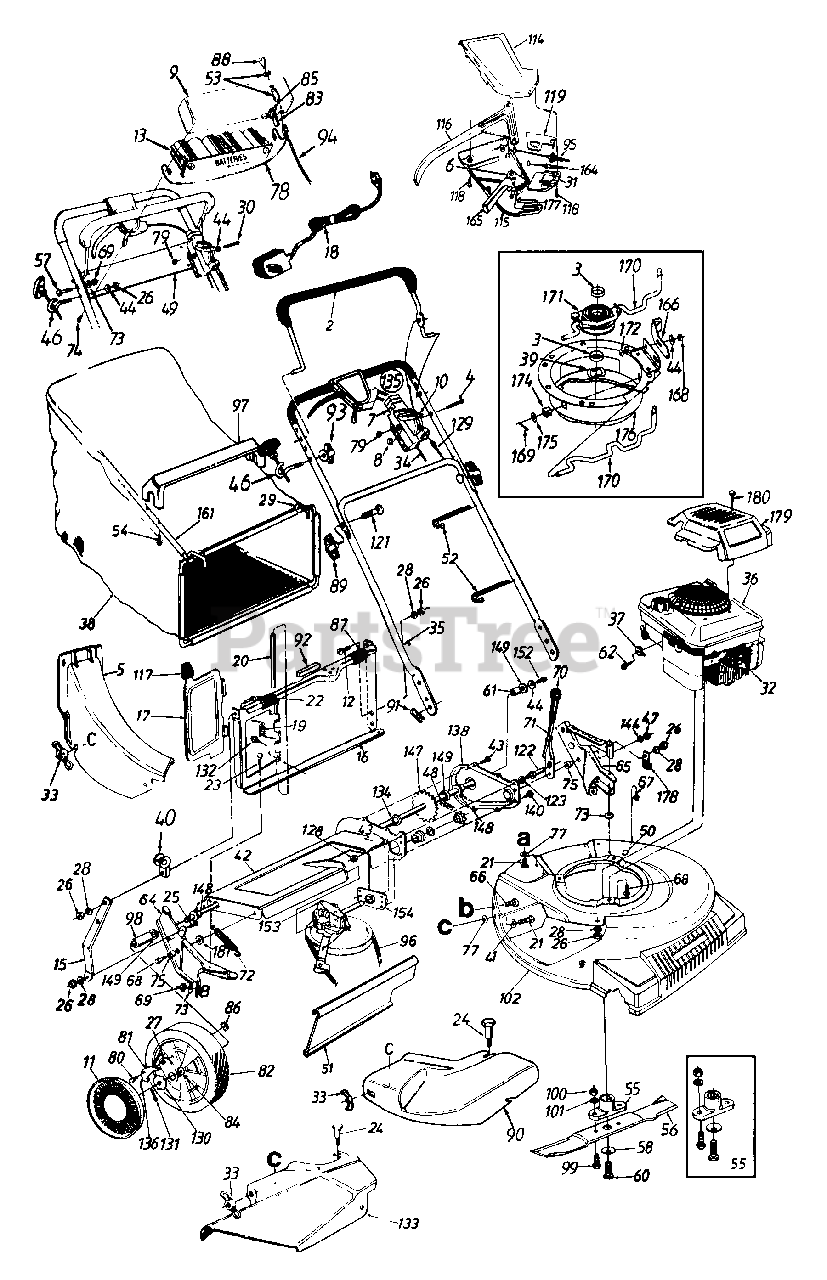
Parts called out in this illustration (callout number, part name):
2	Control Handle
3	Spacer .895" I.D. x 1" O.D.
5	Rear Discharge Chute Ass'y.
6	3 Tooth Rack Gear Insert
7	Throttle Body
8	Spr. Wash..66" I.D.
9	Battery Tray
11	Hub Cap
12	Truss Mach. Scr. 1/4-20 x .62"
13	Battery Pack - 12 Volt
18	Battery Charger
19	Torsion Spring
20	Pivot Pin
21	Carriage Bolt 1/4-20 x .62"
22	Truss Mach. Scr. 1/4-20 x .75"
23	Hex AB-Tap Scr. 1/4-20 x .38"
24	Shoulder Bolt Special
25	Hex Bolt 1/4-20 x .62" Lg.
26	Hex Nut 1/4-20 Thd.
27	Pawl Plate
28	L-Wash. 1/4" I.D.
30	Hex Bolt 1/4-20 x 2" Lg.
31	S.P. Control Cover
32	Spark Plug Insulator
33	Wing Nut
34	Throttle Cable 61"
36	Engine
37	Casing Clamp
38	Grass Bag
39	Wave Wash..88" I.D. x 1.38" O.D.
40	Rope Guide - Lower
41	FI-Wash..344" I.D. x .62"
44	Bell-Wash. 1/4" I.D.
46	Rope Guide - Upper
47	Hex Patch L-Nut 3/8-24 Thd.
48	#48 Chain .500" Pitch x 30 Links
51	Rear Flap
52	Cable Tie
53	Ignition Switch
54	Hex AB-Tap Scr. #12 x 1.25"
55	Blade Adapter Kit
56	21" Mulching Blade
57	Curved Carr. Bolt 5/16-18 x 1.38" Lg.
58	Bell-Wash..39" l.D.
60	Hex Bolt 3/8-24 x 1.5"
61	Spacer .513" I.D.
62	Hex Wash Hd. Scr. 010-32 x .62" Lg.
64	R.H. Handle Wheel Brkt. Ass'y.
65	L.H. Handle Wheel Brkt Ass'y.
66	Carriage Bolt 5/16-18 x .62"
67	Hex B-Tap Scr 5/16-18
68	Hex TT-Tap Scr 3/8-16
69	Hex Nut 5/16-18 Thd
71	Height Adj. Lever
72	Extension Spring 3.80" Lg.
73	Bell-Wash. 5/16" I.D.
74	Truss Mach. Tap Scr .75" Lg.
75	Shld. Spacer .5" Dia.
77	Bolt Retainer 1/4 x .50" 0 D.
78	Wire Harness
79	Hex L-Nut 1/4-20 Thd
80	Shld. Scr. 342" Dia. x .268
81	Pawl - R H
82	Wheel Ass'y Comp.
83	Plugs
84	Sleeve Bearing 1/2" I D.
85	Fuse Holder
86	Flat Nut 1/4-20 Thd.
87	Panel Clip
88	Ignition Key
89	Hand Knob
90	Mulching Plug
91	Hairpin Clip
92	Foam Strip 1/4" x 1" Lg.
93	Wing Nut 1/4-20 Thd (899R)
94	Harness Extension
95	S.P. Cable - 50" Lg
96	"V"-Belt
97	Bag Handle
98	Sleeve .526" I.D.
99	Hex Bolt 3/8-24 x 1.0" Lg
100	Hex Nut 3/8-24 Thd.
101	L-Wash. 3/8" I.D
115	Self-Propelled Control Cover
116	Control Lever
117	Door Grip
118	Fl-"C"-Sunk Hd. Tap Scr #10 x.75" Lg.
119	6-Speed Rack Cable Brkt.
121	Curved Hd Bolt 5/16-18 x 2" Lg.
122	Shld. Pin 1.43" Lg.
123	L-Wash. 3/8" I.D.
128	Hex Jam Nut 3/8-24 Thd.
129	Control Cable - 44"
130	Ratchet Wheel 1.62" O.D
131	Cotter Pin 1/8" Dia. x 1"
132	Hex B-Tap Scr. #10 x .38" Lg.
133	Side Chute Deflector Ass'y.
134	Hex Flange Bearing
136	Spring - Nylon
144	FI-Wash..385" I.D. x .87"
147	Rear Shaft Ass'y. 21.94" Lg.
148	Hex Flange Brg..506" I.D.
149	FI-Wash..531" I.D. x.930"
152	Hex Bolt 1/4-20 x .62" Lg. (Grade 5)
153	Transmission Comp.
164	Spd. Control Cable - 50" Lg
165	6-Spd. Sh ft Lever
169	Cot-Pin 3/32" Dia. x .75" Lg.
170	Shift Rod
171	Pulley Ass'y
172	Carr. Bolt 1/4-20 x .5" Lg.
174	Flanged Bushing
175	FI-Wash..328" I.D. x.68" O.D
176	Housing Ass'y.
177	Shift Lever Spring
179	Engine Cover
180	Screw #10 x 1.25" Lg.
181	FI-Wash. .383" I D x 1" O.D
